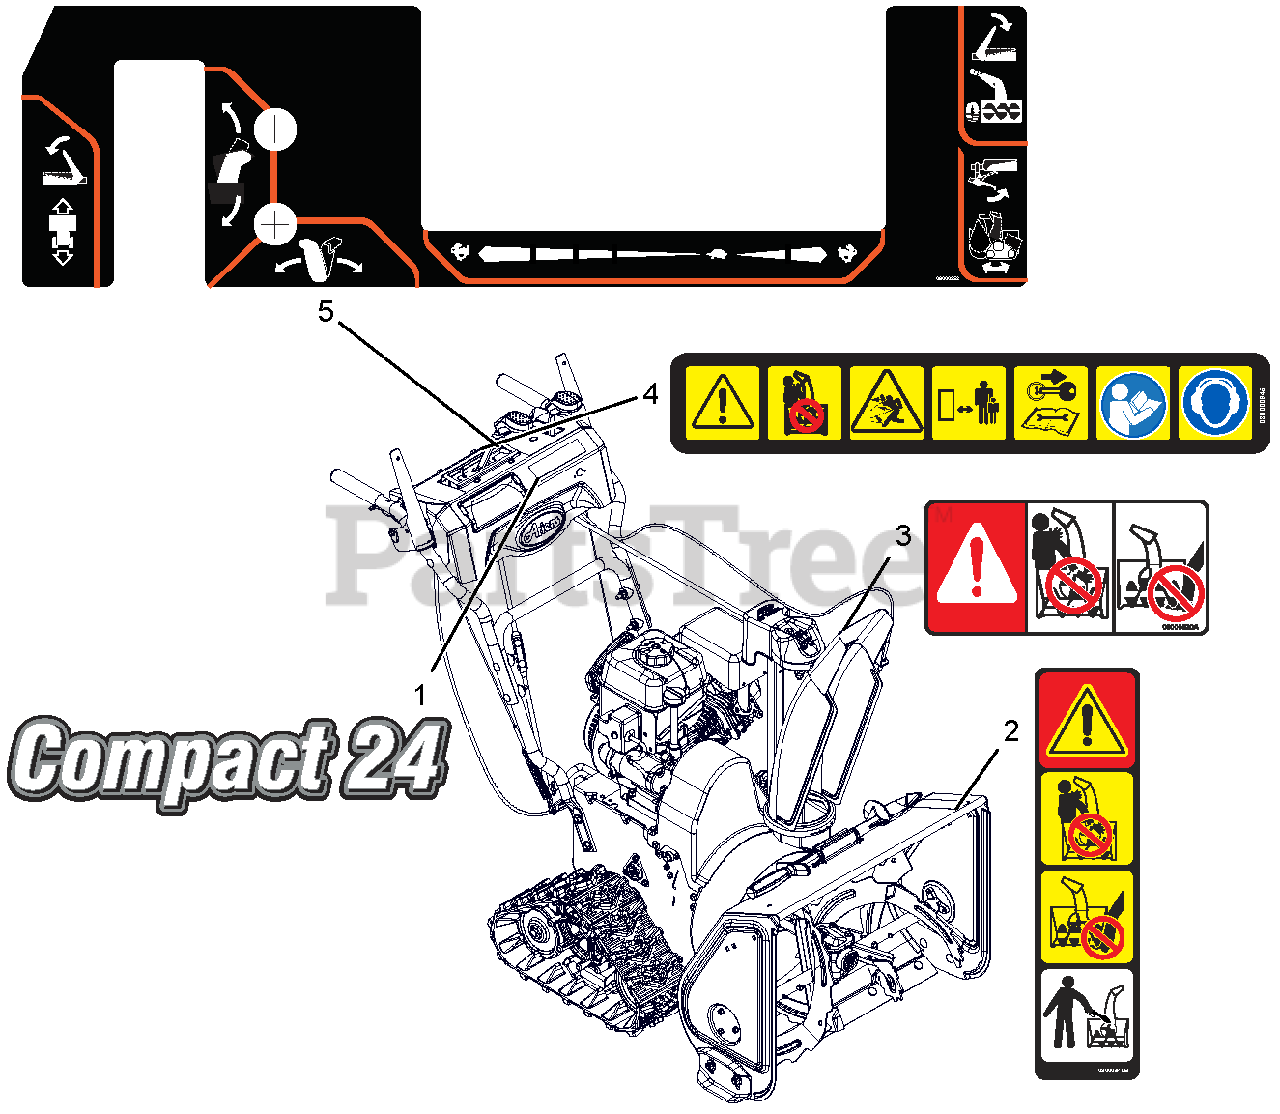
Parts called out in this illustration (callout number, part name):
1	DECAL, COMPACT 24
2	DECAL, DANGER - ROTATING PARTS
3	DECAL, DANGER
4	DECAL,DASH - SAFETY
5	DECAL,CONTROL-COMP TRACK
